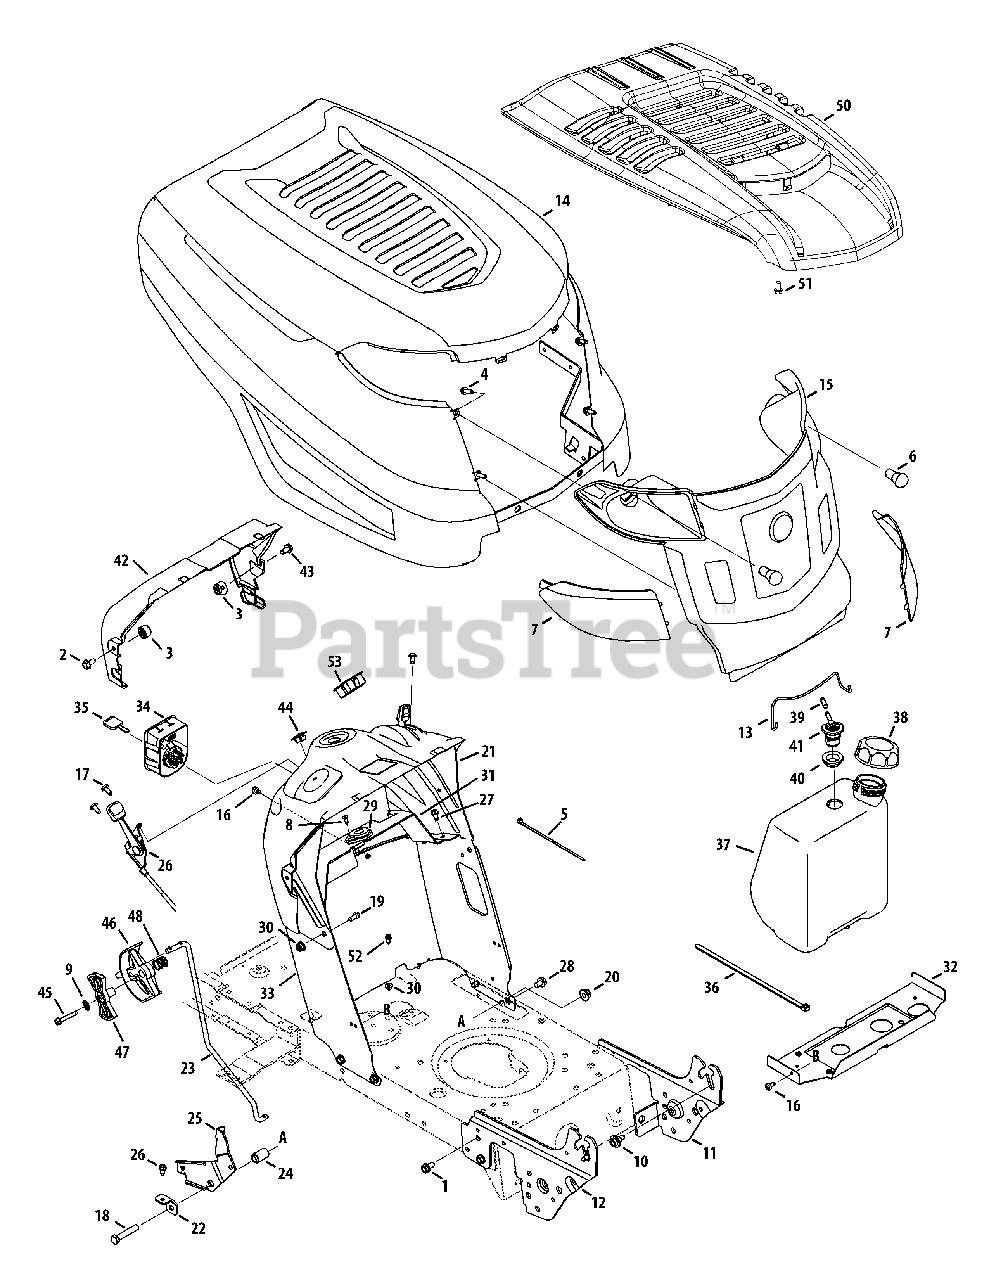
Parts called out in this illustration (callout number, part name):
1	Screw 5/16-18 x .75
2	Screw #12-16 x 1.5
3	K-Style Bumper
4	Screw 1/4 x .750
5	Cable Tie
6	Miniature Lamp 12V Socket
7	Grill Lens - LH
7	Grill Lens - RH
8	Screw, #10-16 x .50
9	Lockwasher 1/4ID
10	Shoulder Screw 5/16-18 x .43 x .29
11	Left Support Pivot Bracket
12	Right Support Pivot Bracket
13	Battery Rod
15	Grille Ass’y
16	Self-Tapp Screw 1/4-20 x .50
17	Self-Tapp Screw 1/4-20 x .50
18	Hex Screw 3/8-16 x 2.0 Gr. 5
19	Screw 5/16-18 x .625
20	Hex L-Flg. Nut 3/8-16 Gr. F, Nylon
21	Upper Dash (3 pc w/ Amm. & RMC)
22	Speed Latch
23	Speed Selector Control Rod
24	Flange Spacer
25	Speed Latch Bracket (w/RMC)
26	Tap Screw 1/4-20 x 0.625
28	Screw 5/16-18 x .675
29	Bearing .628 ID x 1.36
30	Flange Locknut 5/16-18 Gr. F, Nylon
31	Steering Support Bracket
32	Gas Tank Support Bracket
33	Dash, Lower
34	3 Position Key Switch
36	Cable Tie
37	Fuel Tank 1.36 gal.
38	Cap-Fuel
39	Hose Vent
40	Rubber Grommet
41	Rollover Valve
43	Hi-Lo Screw 1/4-15 x .75
44	Choke Plug
45	Hex Washer Scr. 1/4-20 x 1.50
46	Shift Lever
47	Index Control
48	Compression Spring .685 OD x .63
50	Hood Scoop - Troy
51	Hex Hi Lo Scr. 1/4-15 x .50
52	Hex TT Scr. 5/16-18 x .625
53	Ammeter Plug
